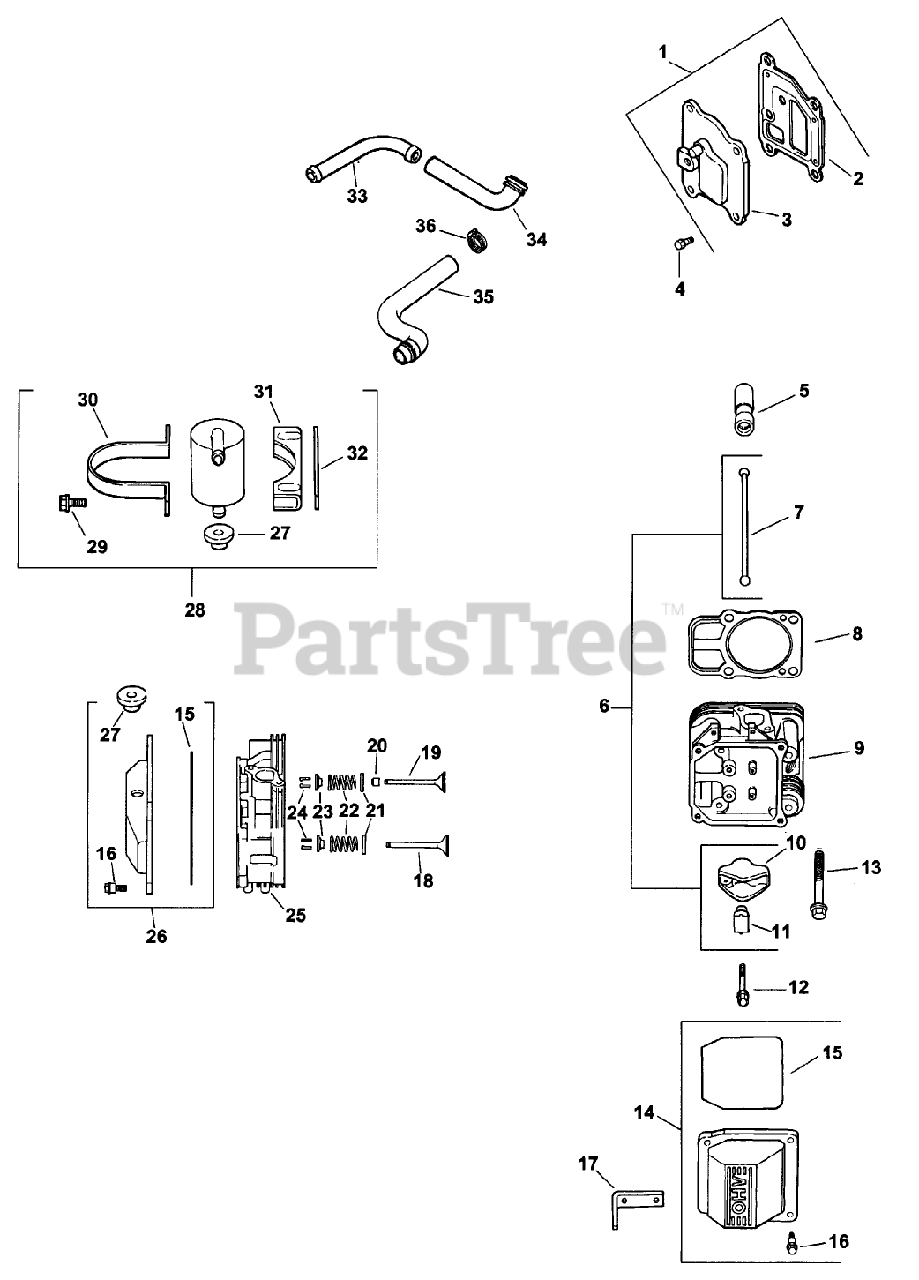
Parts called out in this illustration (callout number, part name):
1	Kit, breather cover w/gasket (Incl. 2,3)
2	Gasket-Breather
3	Cover, breather
4	Screw
5	Lifter-Valve
6	Kit, valve train (Includes 7,10,11)
7	Rod-Push
8	Gasket-Cylinder Head
9	#2 Cyl. Head Asm,
10	Arm-Rocker
11	Pivot-Arm, Rocker
12	Screw
13	Screw
14	Kit, valve cover-plain (Includes 15,16)
15	O-Ring
16	Screw
17	Strap-Lifting
18	Valve-Exhaust
19	Valve-Intake
20	Seal-Stem, Valve
21	Retainer-Spring
22	Spring-Valve
23	Cap-Spring, Valve
24	Retainer Kit
25	#1 Cyl. Head Asm
26	Kit,valve coverbreather(Incl. 15,16,27)
27	Grommet-Rubber
28	Kit, breather separator (Includes 27,29-32)
29	Screw-HF
30	Strap-Lifting
31	Bracket
32	Spacer
33	Fitting
34	Hose-Breather
35	Hose-Breather
36	Clamp
